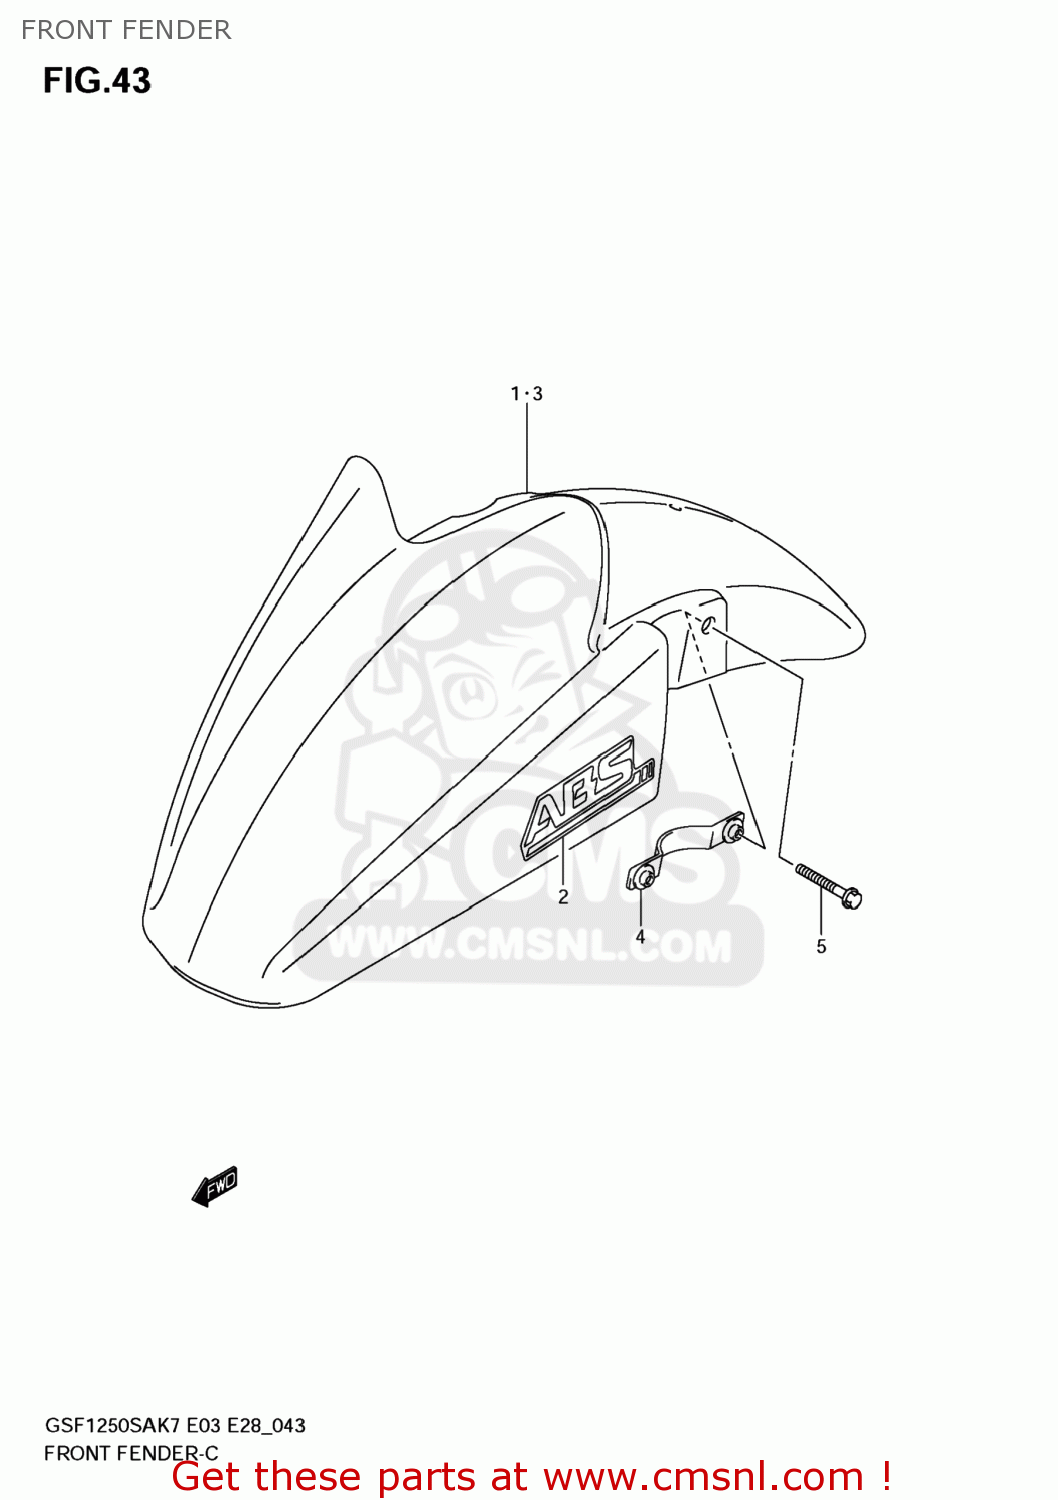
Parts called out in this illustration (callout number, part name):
1	FENDER,FR
2	EMBLEM,ABS
3	FENDER,FR
4	PLATE,FR FENDER
5	BOLT(6X35)
